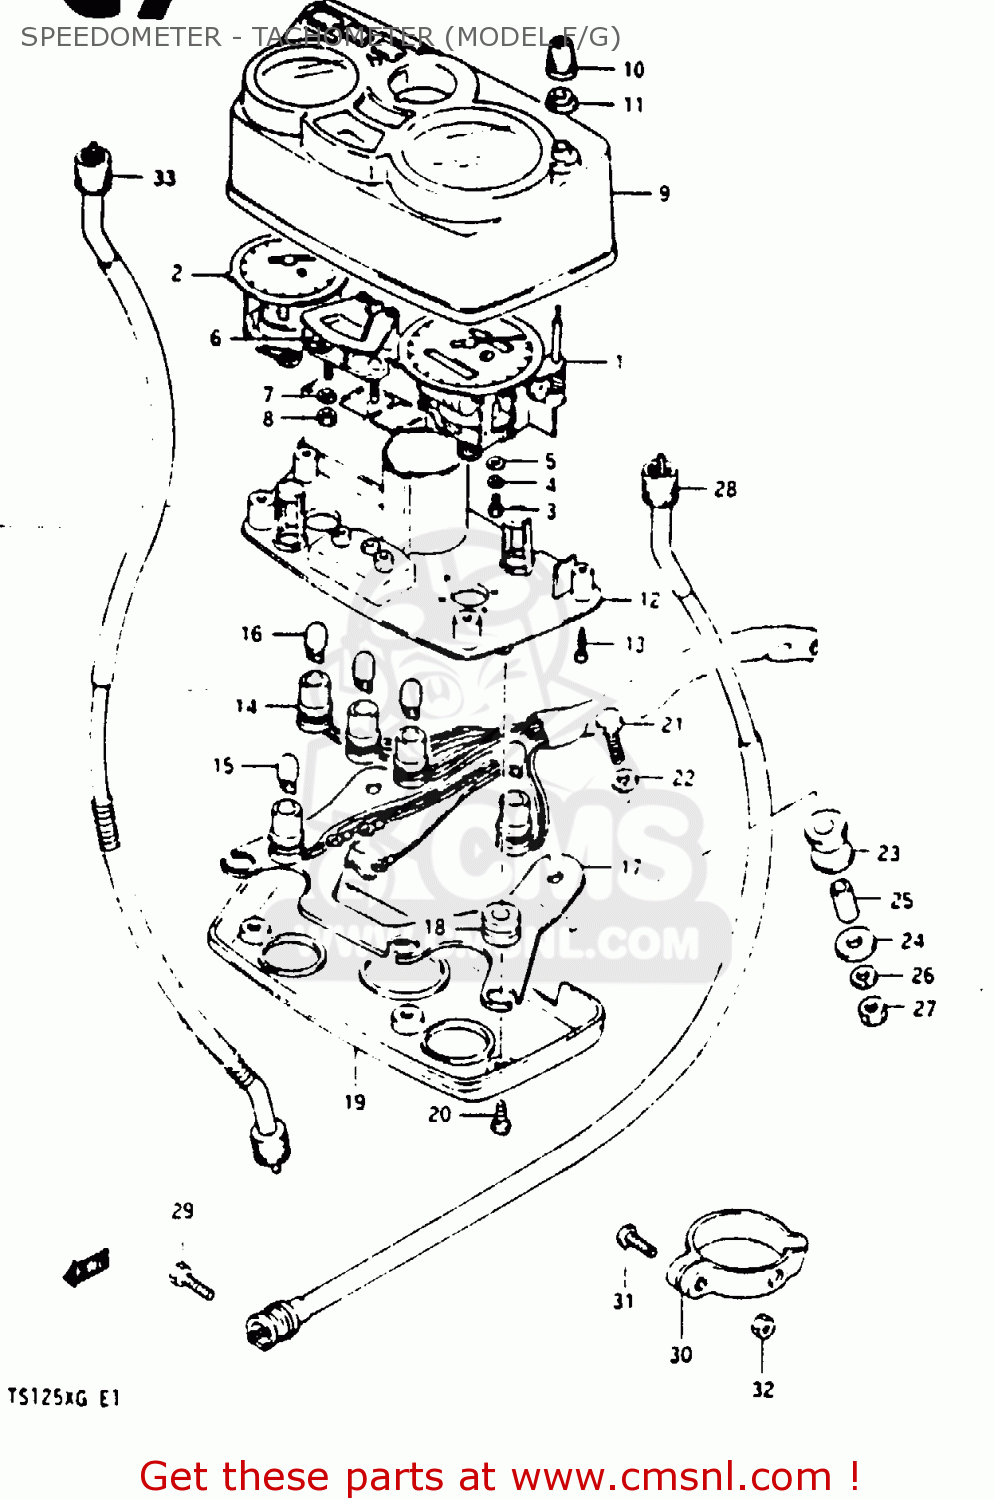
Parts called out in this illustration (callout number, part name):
1	SPEEDOMETER (MILE/KILO)
2	TACHOMETER
3	SCREW
4	LOCK WASHER
5	WASHER 3.3X8X0
6	GAUGE, WATER TEMPERATURE
7	LOCK WASHER
8	NUT
9	HOOD, METER
10	KNOB,TRIP METER
11	SEAL,TRIP KNOB
12	CASE,METER
13	SCREW
14	SOCKET, METER
15	BULB(12V3.4W,T10,BF175-01450A)
16	BULB(12V1.7W,T10,WB121)
17	BRACKET,METER
18	CUSHION
19	COVER, LOWER
20	SCREW
21	BOLT
22	WASHER,LOCK
23	CUSHION
24	WASHER (6.5X18X1.6)
25	SPACER (6.1X8X15.5)
26	LOCK WASHER
27	NUT
28	CABLE, SPEEDOMETER
29	BOLT
30	CLAMP,SPEEDOMETER CABLE
31	SCREW
32	NUT ,5MM
33	CABLE ASSY,TACHOMETER
